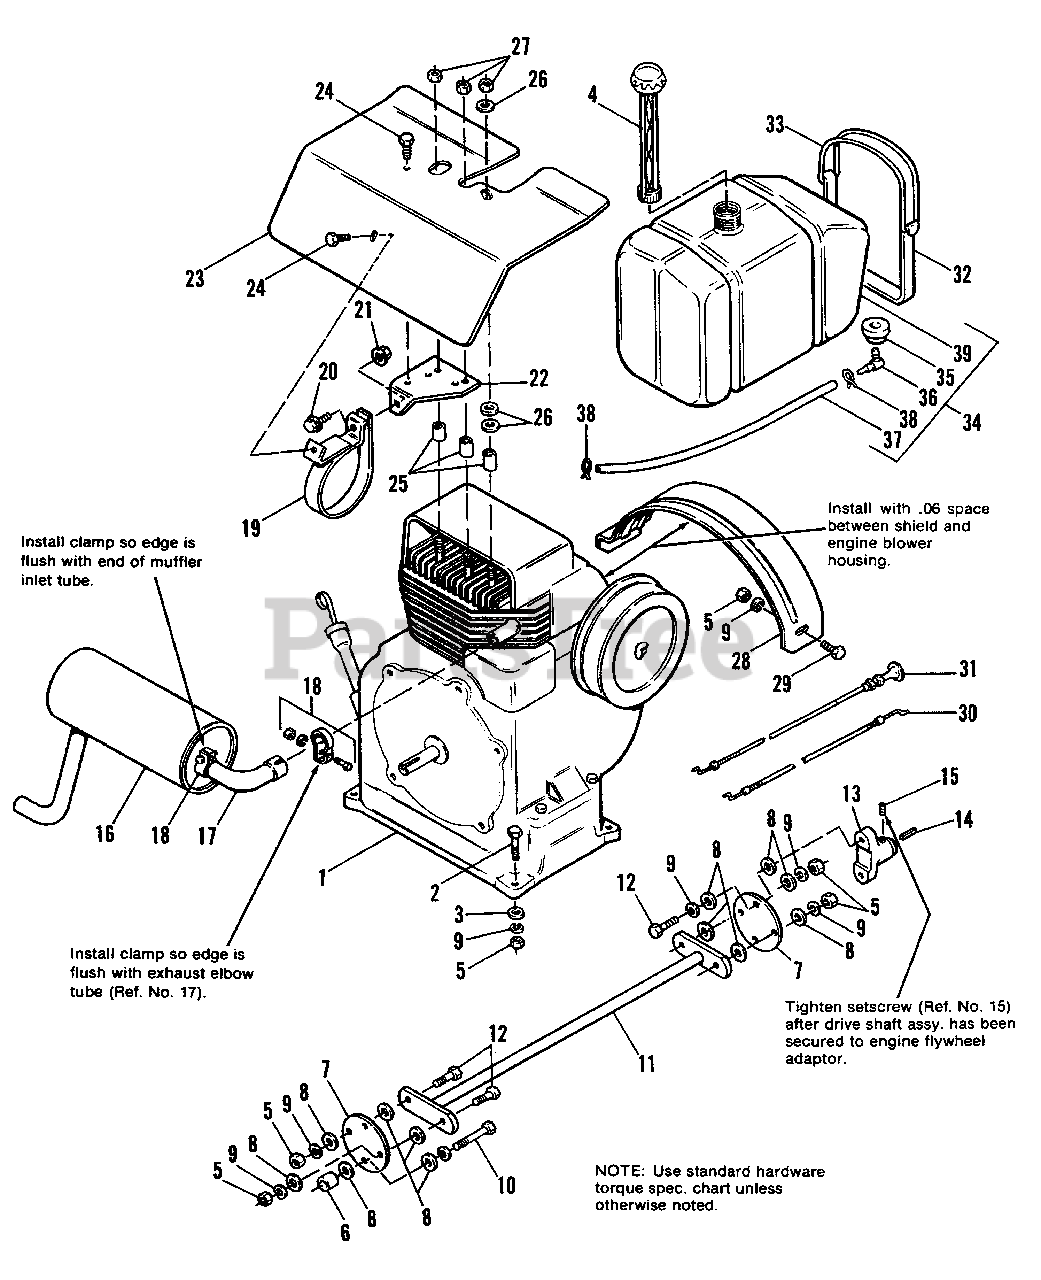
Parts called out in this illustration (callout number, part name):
1	ENGINE, 10 H.P. Kohler
2	CAPSCREW, Hex Hd., 3/8-16 x 1-1/2
3	WASHER, 3/8
4	CAP, Fuel Tank, Gauge
5	NUT, Hex, 3/8-16
8	WASHER, Special
9	LOCKWASHER, 3/8
10	CAPSCREW, Hex Hd., 3/8-16 x 2-1/4
11	SHAFT ASSY., Drive
12	CAPSCREW, Hex Hd., 3/8-16 x 1-1/4
13	FLANGE, Drive Shaft
14	KEY, Drive Shaft
15	SETSCREW, 3/8-24 x 3/8
16	MUFFLER, Exhaust
17	ELBOW, Exhaust
18	CLAMP, Muffler
19	STRAP ASSY., Muffler
20	CAPSCREW, Hex, Flange, Whiziock, 5/16-18 x 1-1/2
21	LOCKNUT, Hex, Flange, Whiz, 5/16-18
22	SUPPORT, Muffler
23	SHIELD, Heat
24	SCREW, Hex Hd., Taptite, 1/4-20 x 1/2
27	LOCKNUT, Jam, 3/8-16
29	CAPSCREW, Hex Hd., 3/8-16 x 3/4
30	CONTROL, Throttle
31	CONTROL, Choke
32	STRAP, Tank
33	STRAP, Fuel Tank
34	FUEL TANK ASSY.
38	CLAMP, Hose
